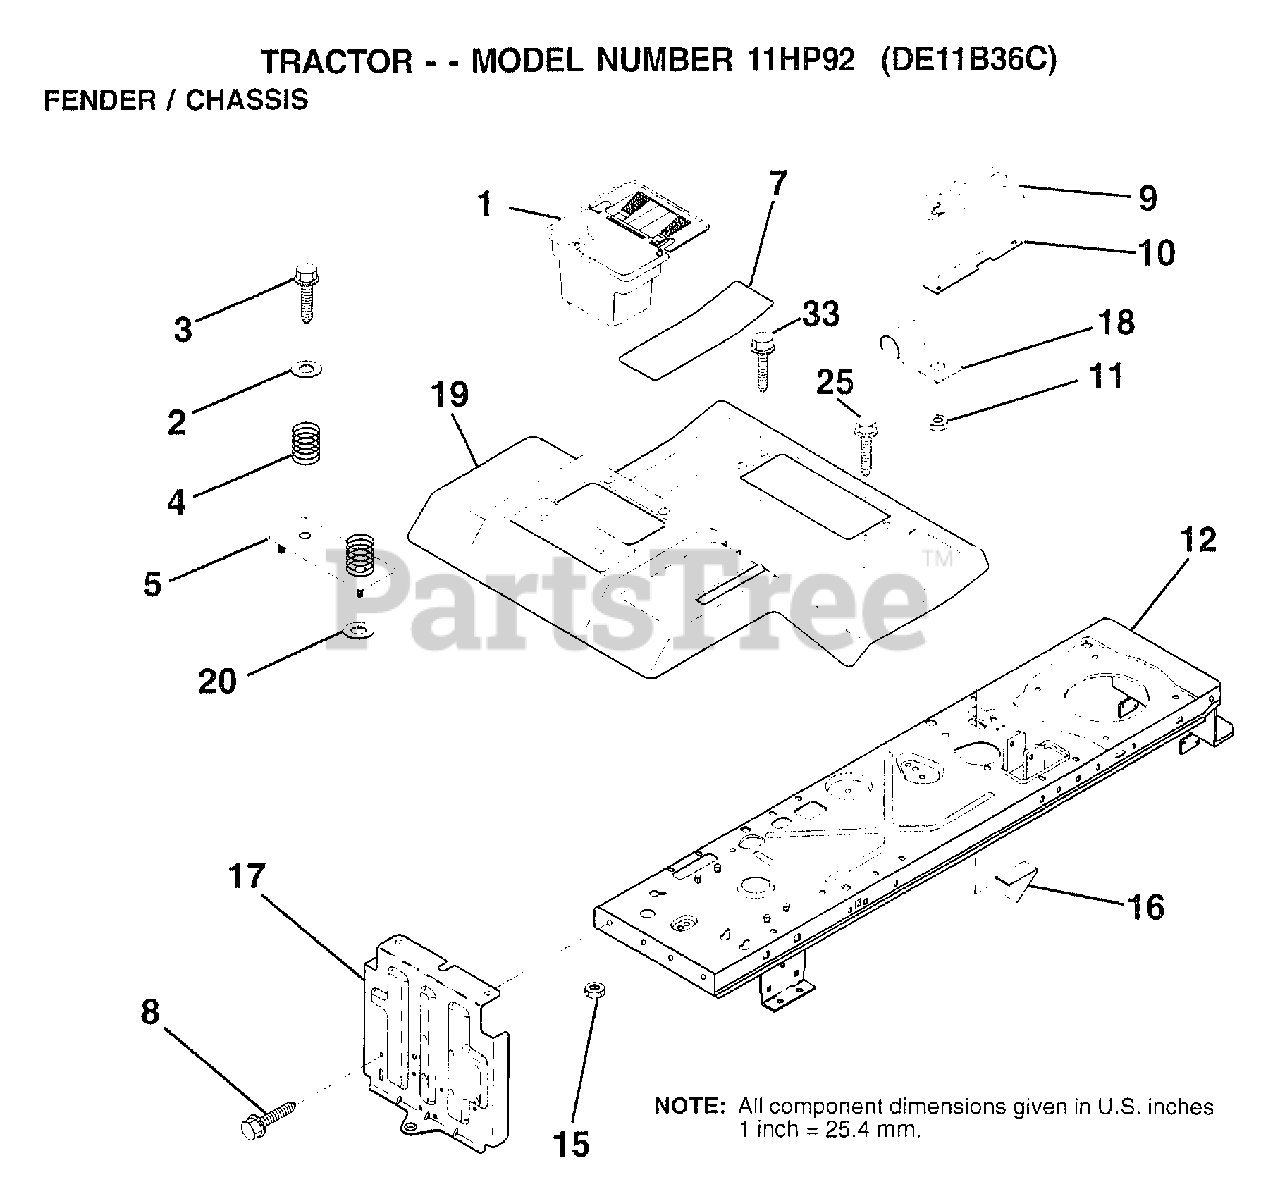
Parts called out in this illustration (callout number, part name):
1	"CASE,BATTERY.MECH"
2	WASHER
3	SCREW
4	SPRING COMPRESSIO
5	PLATE, BATTERY
7	PAD FOOTREST
8	SCREW
9	CONSOLE.SHT.4SP.
10	PLATE LOCK SHIFT
11	NUT
12	CHASSIS.WELD.ASM.
15	NUT HXKEP 1/4X20
17	DRAWBAR ASM LR
18	"CLIP,INSULATOR"
19	FENDER.FOOTREST
25	SCREW TAPPING
33	SCREW
